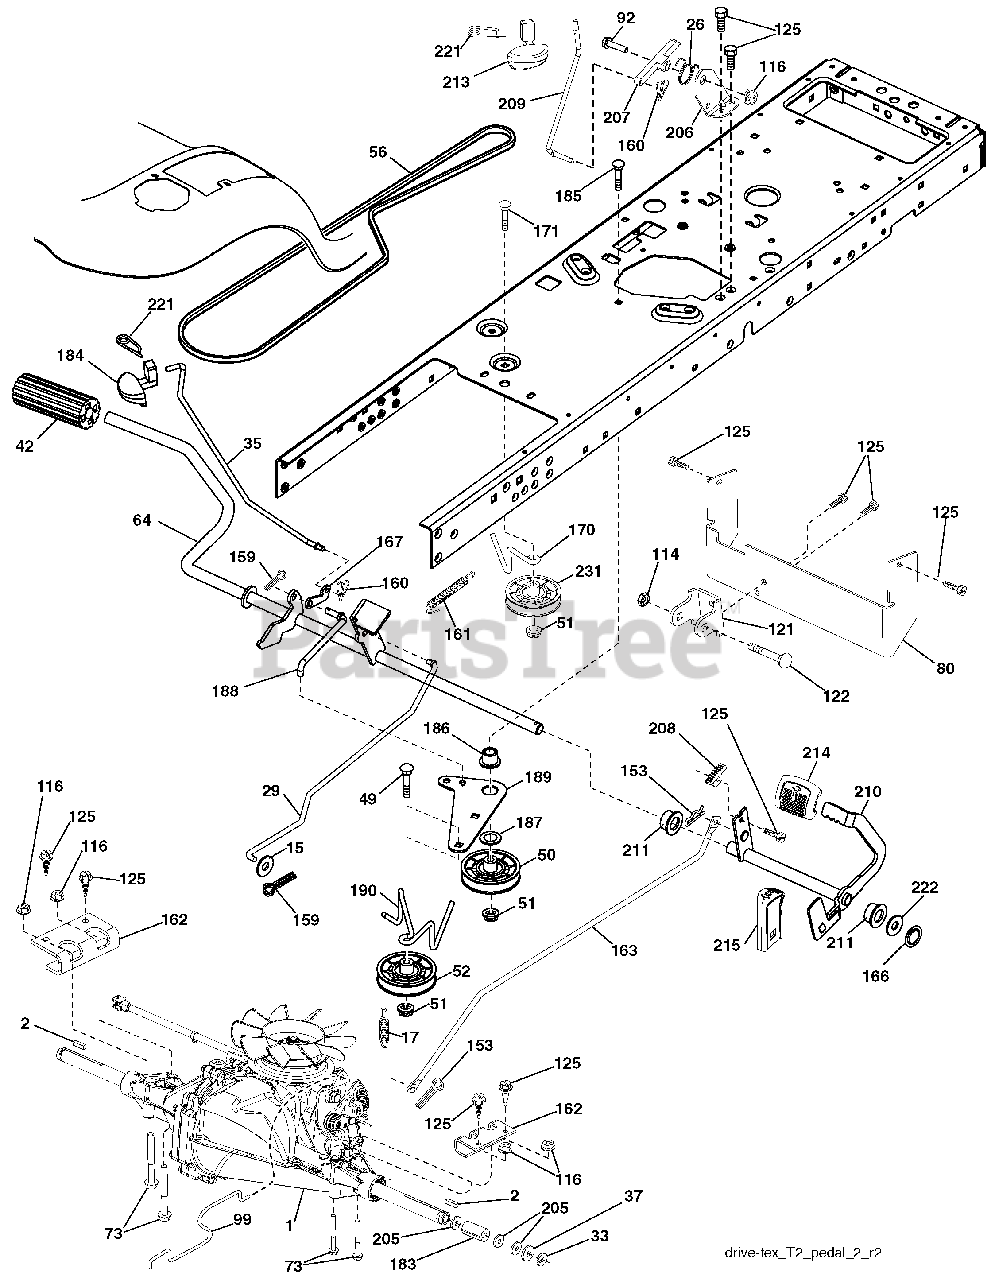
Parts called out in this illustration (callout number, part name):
2	Key
15	Washer 13/32 x 13/16 x 16 Ga.
17	Spring, Brake
26	Spring Return Cruise
29	Rod, Brake
33	Ring E
35	Rod, Brake, Park
37	Washer 25/32 x 1-1/4 x 16 Ga.
42	Cover, Foot Pedal
49	Bolt
50	Pulley Idler Flat
51	Lock Nut 3/8-16
52	Idler V-Groove 910" Offset
56	V-Belt, Drive
64	Shaft Asm. Pedal Brake Control
73	Bolt 5/16-18 Gr. 5
80	Strap Torque
92	Bolt Fin Hex 5/16-18 unc x 1.25
99	Rod Asm Bypass Spring
114	Nut Lock 5/16-18 unc
116	Nut Lock Hex Flange 5/16-18
121	Bracket Strap Torque
122	Bolt 5/16-18 x 2.50
125	Screw 5/16-18 x 3/4
153	Retainer Spring
159	Pin Cotter 1/8 x 3/4
160	Retainer Clip
161	Spring, Return, Clutch
162	Adapter Transaxle
163	Rod Pedal Control
166	Nut Push .625
167	Latch Brake Parking
170	Keeper Belt Centerspan
171	Bolt
183	Spacer Axle
184	Handle Parking Brake
185	Bolt
186	Spacer Retainer
187	Washer
188	Link Clutch Ground Drive
189	Bellcrank Ground Drive
190	Keeper Bellcrank Ground Drive
205	Washer 25/32 x 1-5/8 x 16 Ga.
206	Bracket Mount Latch Cruise
207	Latch Control Cruise
208	Gear Sector Control Cruise
209	Rod Control Cruise
210	Rockr Asm. Pdeal Control
211	Bearing Nylon
213	Knob control Cruise
214	Pad Pedal Forward
215	Pad Pedal Reverse
221	Retainer Spring Clip Handle
222	Washer 21/32 x 1-1/4 10 Ga.
231	Idler V-Groove 1.688
